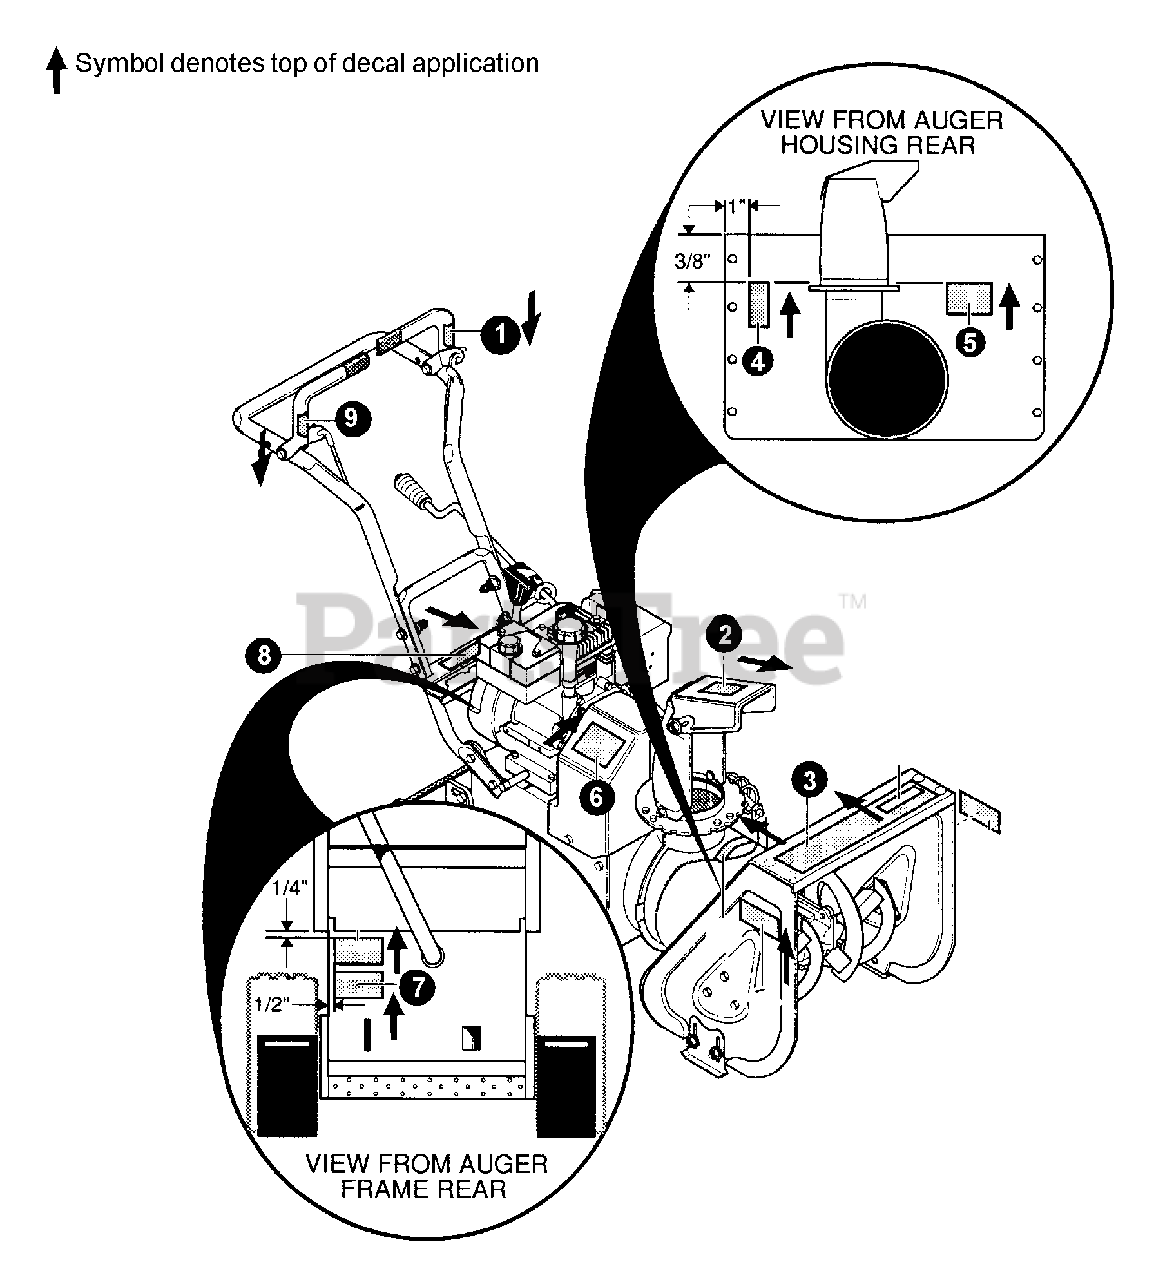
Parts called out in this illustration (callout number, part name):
1	LABEL - TRACTION DRIVE ENGAGE
2	LABEL - DANGER
3	LABEL - ECHO
4	LABEL - DANGER
5	LABEL - DANGER
6	LABEL - BELT ADJUSTMENT
7	LABEL - DISC ADJUSTMENT
8	LABEL - GEAR SELECTOR
9	LABEL - AUGER DRIVE ENGAGE
